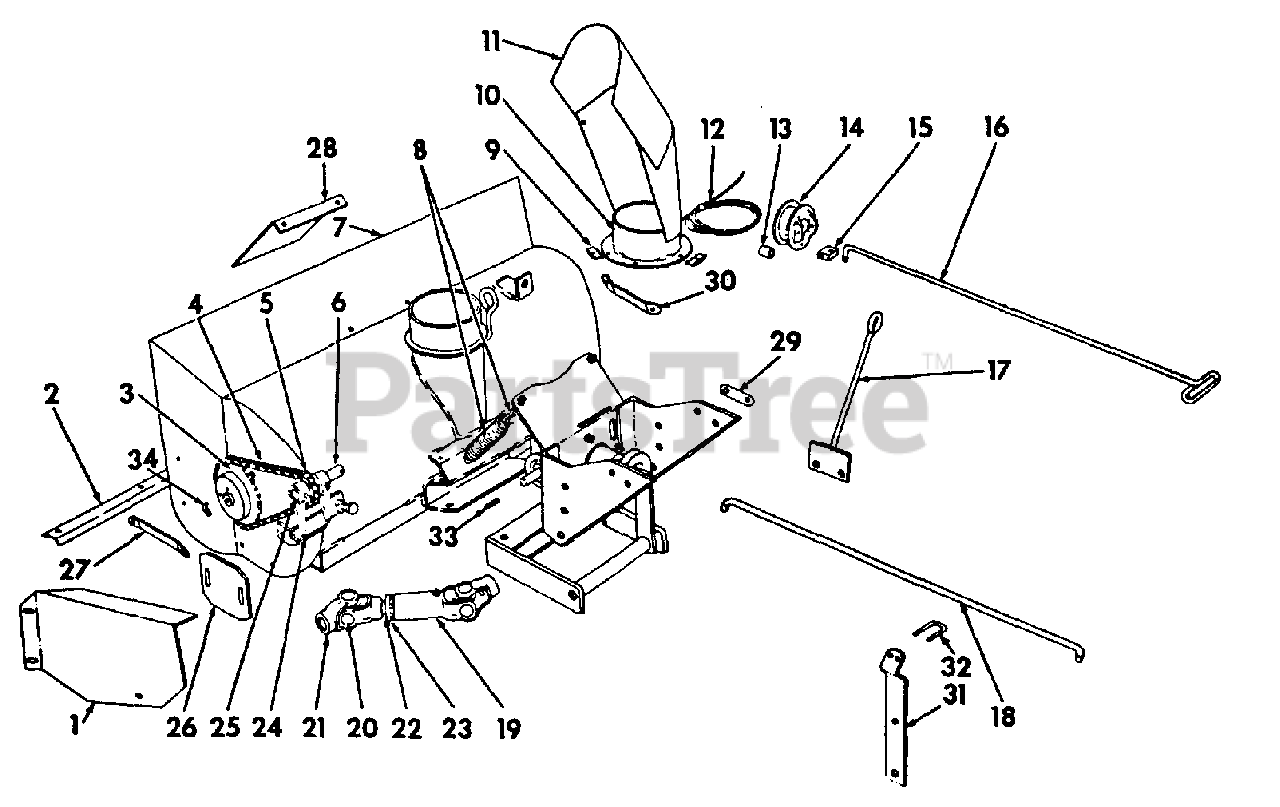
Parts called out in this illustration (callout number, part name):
1	GUARD. CHAIN
3	SPROCKET - 24T
3	SPROCKET -24T
4	CHAIN, ROLLER - FOR 24 T SPROCKET-
5	SPROCKET - SMALL
6	SHAFT, TRANSFER
8	SPRING, TENSION
9	CLIP, CHUTE HOLDER
10	CHUTE ASSY, SNOW
11	CAP, DEFLECTOR
12	CABLE SWIVEL CONTROL
14	SPOOL, SWIVEL
16	ARM, CONTROL
17	BRACKET, CONTROL ARM SUPPORT
18	ROD. LIFT -WILL WORK FOR IH-47557881-
19	JOINT ASSY, UNIVERSAL -TRACTOR HALF-
20	KIT, UNIVERSAL JOINT
21	JOINT ASSY, UNIVERSAL -BLOWER HALF-
22	RETAINER. GREASE
23	CAP, RETAINER
24	BRACKET, SPROCKET MOUNTING
25	BEARING ASSY, NEEDLE
27	STRAP, SUPPORT LH
28	PLATE, DEFLECTOR
29	CLIP, MOUNTING
30	STRAP, SUPPORT - RH
31	BRACKET, LIFT ROD
32	U-BOLT -USED W/BRACKET IH-475611-R1
32	U-BOLT -USED W/BRACKET IH-485469-R1
33	KEY, 3/16 X 11/16 SO PARALLEL
34	RETAINER, SHEAR PIN -SERIAL NO. 11101 AND ABOVE-
